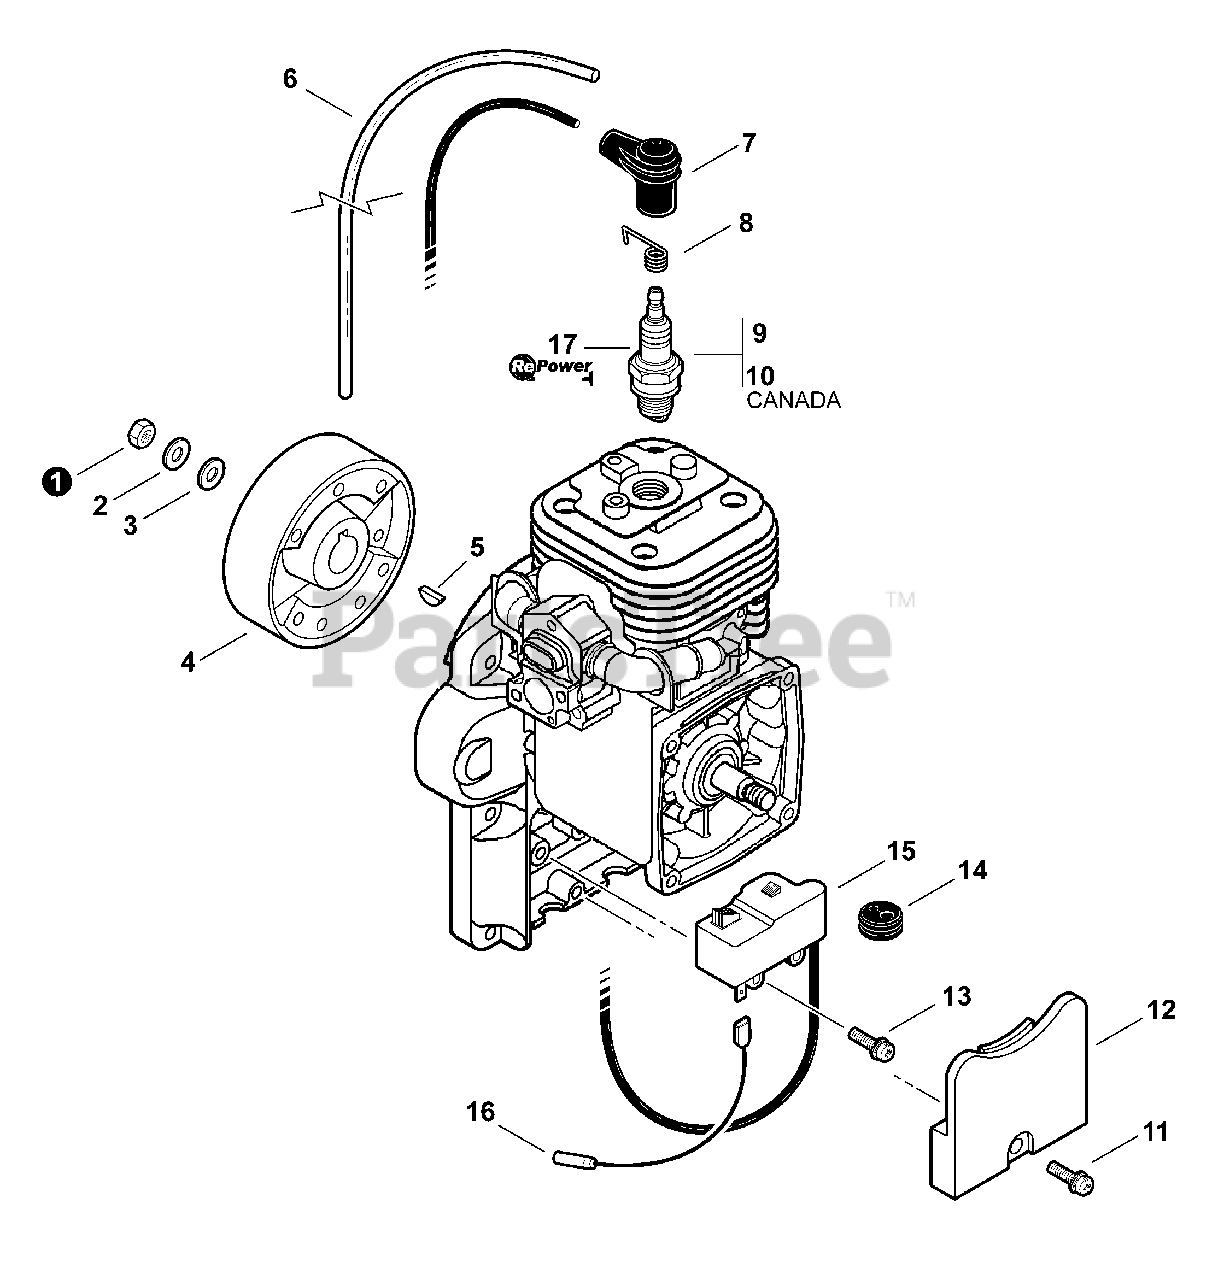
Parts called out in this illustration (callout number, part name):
2	WASHER, SPRING 10
3	WASHER, SPRING 10
4	FLYWHEEL
5	KEY, WOODRUFF 3×14
6	TUBE, VINYL 6.3×8×380
7	CAP, SPARK PLUG
8	TERMINAL, SPARK PLUG
9	SPARK PLUG - BPM8Y
10	SPARK PLUG - BPMR8Y
11	SCREW 5×18
12	COVER, DUST
13	SCREW 5×18
15	COIL, IGNITION
16	LEAD - IGNITION
17	TUNE-UP KIT - REPOWER
